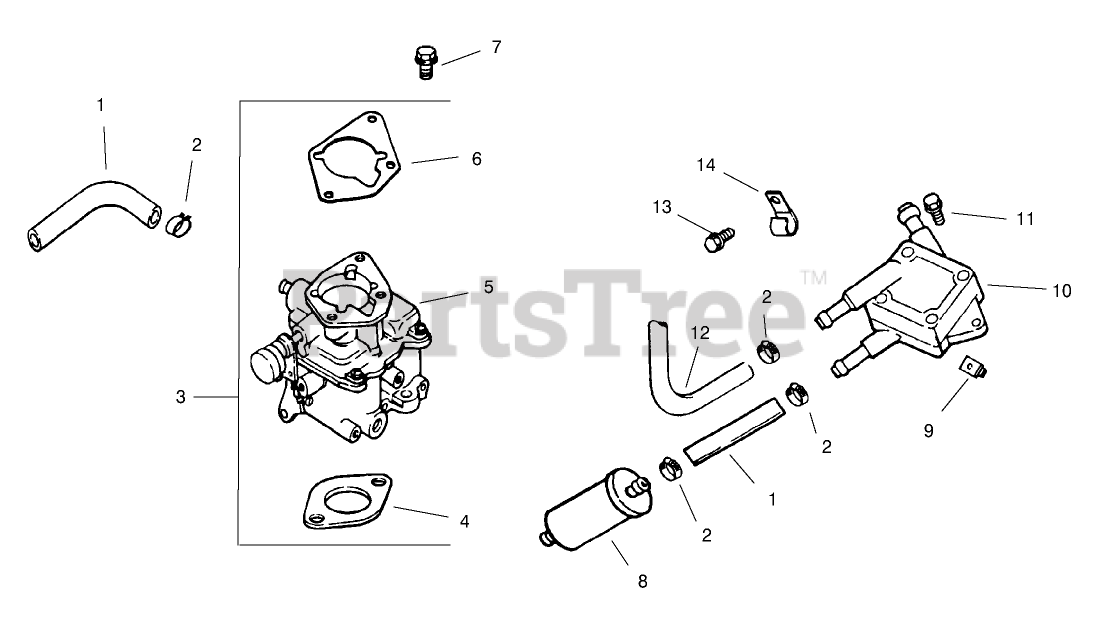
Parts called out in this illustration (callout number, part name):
1	Line-Fuel (9.5)
2	CLAMP-HOSE, SPRING (1/2)
3	Kit, carburetor w/gasket (Incl. 4-6)
4	GASKET-BASE, AIR CLEANER
5	Carburetor ASM(Includes 25 757 01-S,24 757 02-S,24 757 03-S, &24 757 07-S)
6	Gasket-Carburetor
7	SCREW-FLANGE (M6X1.0X30)
8	Filter-Fuel
9	Nut-Plastic
10	PUMP-FUEL
11	SCREW-TAP (M6X1.7X18)
12	Line-Fuel, Flexible (15.5)
13	Screw-HF (M6x1.0x12)
14	CLIP-CABLE
